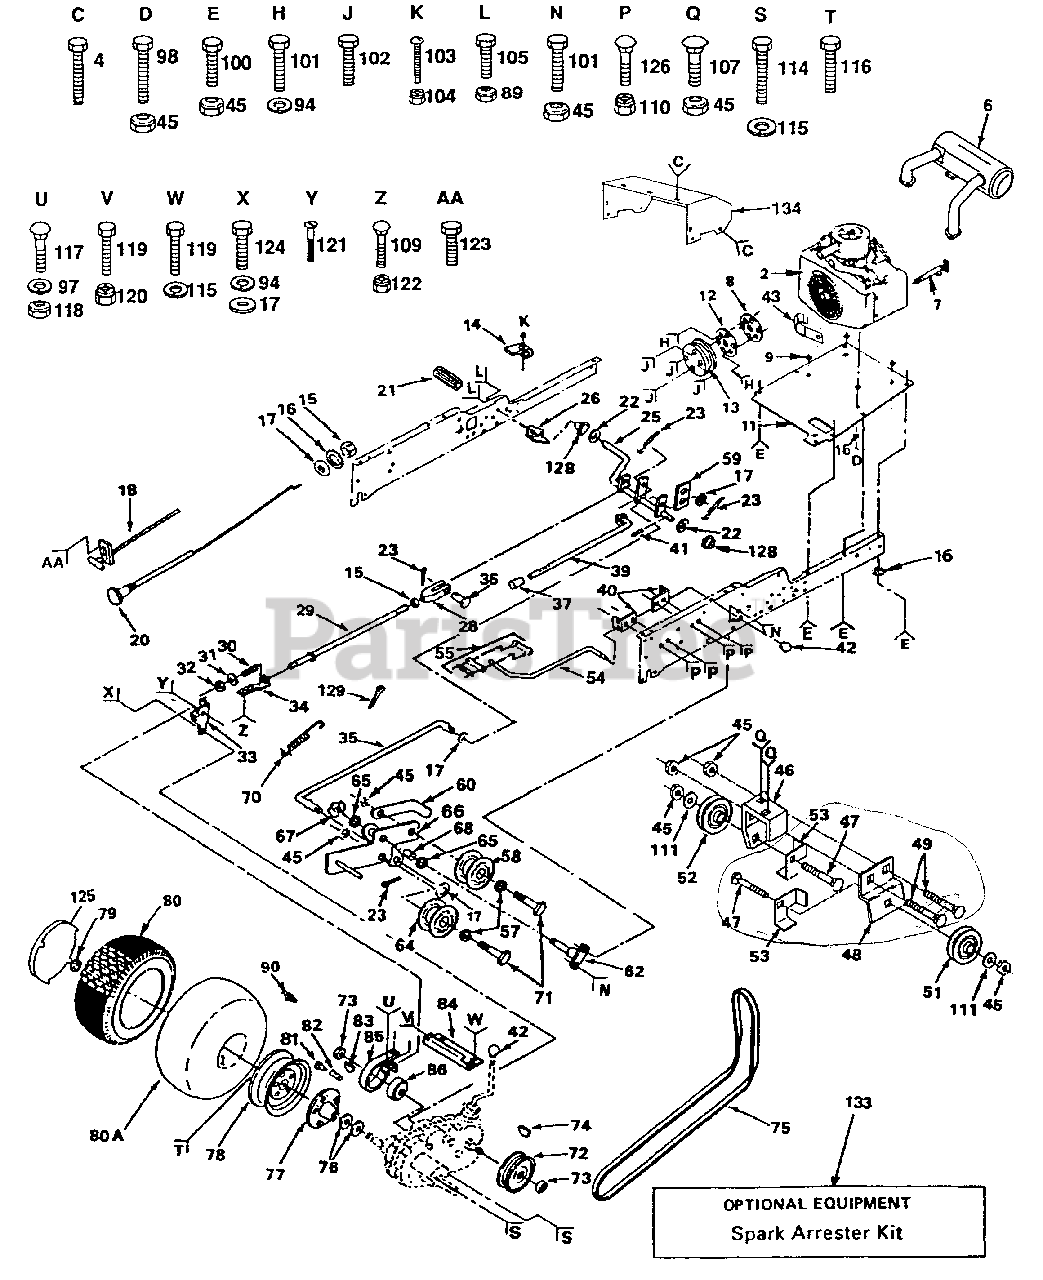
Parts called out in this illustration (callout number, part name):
2	Engine - 18 H.P. Kohler
4	Screw, Hex Thd. Cut 1/4 - 20 x 1/2
6	Muffler - Exhaust
7	Oil Drain Valve
8	Chaff Guard
11	Base - Engine
13	Pulley - Ground Drive
14	Actuator - Switch, Interlock
15	Nut - Hex, 3/8-24
16	Washer, Lock Ext. Tooth, 3/8
17	Washer, 13/32 x 13/16 x 16 Ga.
18	Control, Throttle
20	Control, Choke
21	Cover, Pedal
22	Washer, 25/32 x 1-1/4 x 16 Ga.
23	Pin, Cotter, 3/32 x 3/4
25	Shaft, Foot Pedal
26	Bracket, Interlock
29	Rod, Brake
30	Spring, Compression
31	Washer, 13/32 x 1 x 14 Ga.
32	Nut-Lock, 3/8- 24
33	Bracket, Brake
34	Guide, Rod, Brake
35	Rod, Clutch
36	Pin, Clevis
37	Cap, Plunger
39	Rod, Parking Brake
40	Bracket, Rod, Shift
41	Pin, Roll, 3/16 x 1-1/4
43	Clip, Insulated
45	Nut, Lock, 3/8 - 16
46	Bracket, V-Pulley, Drive, Mule
47	Bolt, Carriage, 3/8 - 16 x 1-3/4
48	Bracket, Idler, Flat
49	Bolt, Carriage, 3/8 - 16 x 3/4
51	Idler, Flat
52	Pulley, Idler
53	Keeper, Belt
54	Rod - Shift, Hi - Lo
55	Connecting Link, Spring Clip
57	Washer, 13/32 x 7/8 x 13 Ga
58	Idler, Flat
59	Retainer, Spring
60	Retainer, Belt
62	Bracket Assembly - Clutch
64	Idler, Grooved
65	Washer, Hardened
66	Bracket, Clutch W/Bearing
67	Klip, Ring
68	Bearing, Idler
70	Spring, Extension
71	Bolt, Hex 3/8-16 x 1-3/4
72	Pulley, Transaxle
73	Nut, Lock, 1/2-20
74	Key, Woodruff 3/16 x 5/8
76	Washer, Thrust, Axle
77	Bushing Assembly and Wheel Hub
78	Rim Assy. Rear
79	Klip, Ring
80	Tire, Rear
80A	Tube, Rear
81	Cap, Valve
82	Stem, Valve
83	Key, Woodruff No. 9 (3/16 x 3/4)
84	Bracket, Support, Transaxle
85	Band, Brake
86	Drum, Brake
89	Nut, Crownlock 1/4-20
90	Fitting, Grease
94	Lockwasher, 3/8
97	Lockwasher, 1/4
98	Bolt - Hex 3/8-16 x 1-1/4 Gr. 5
100	Bolt, Hex 3/8-16 x 3/4
101	Bolt, Hex Head 3/8-16 x 1 Gr. 5
102	Screw, Hex 5/16-18 x 1
103	Screw - Fin 10-24 x 1
104	Nut. Lock No. 10-24
105	Bolt-Hex Head 1/4-20 x 3/4
107	Bolt, Carriage 3/8-16 x 3/4 Gr. 5
109	Bolt, Carriage 5/16-18 x 3/4
110	Nut, Lock 5/16-18
111	Washer, 13/32 x 1 x 12 Ga.
114	Bolt, Hex 7/16-14 x 1-1/4
115	Lockwasher, 7/16
116	Bolt, Hub
117	Bolt, Carriage, 1/4-20 x 5/8
118	Nut-Hex 1/4 - 20
119	Bolt-Hex 7/16 - 14 x 1
120	Nut-Crown lock 7/16 - 14
121	Screw, Mach. Udrcut. Flat Head, 3/8 - 16 x 3/4
122	Nut, Lock 5/16-18
123	Screw, Hex 1/4-20 x 1/2
124	Bolt, Hex 3/8-16 x 7/8
125	Cover, Wheel
126	Bolt-Carriage 5/16-18 x 3/4
129	Pin, Cotter 1/4 x 1
133	Spark Arrester Kit
134	Duct, Exhaust, Upper
